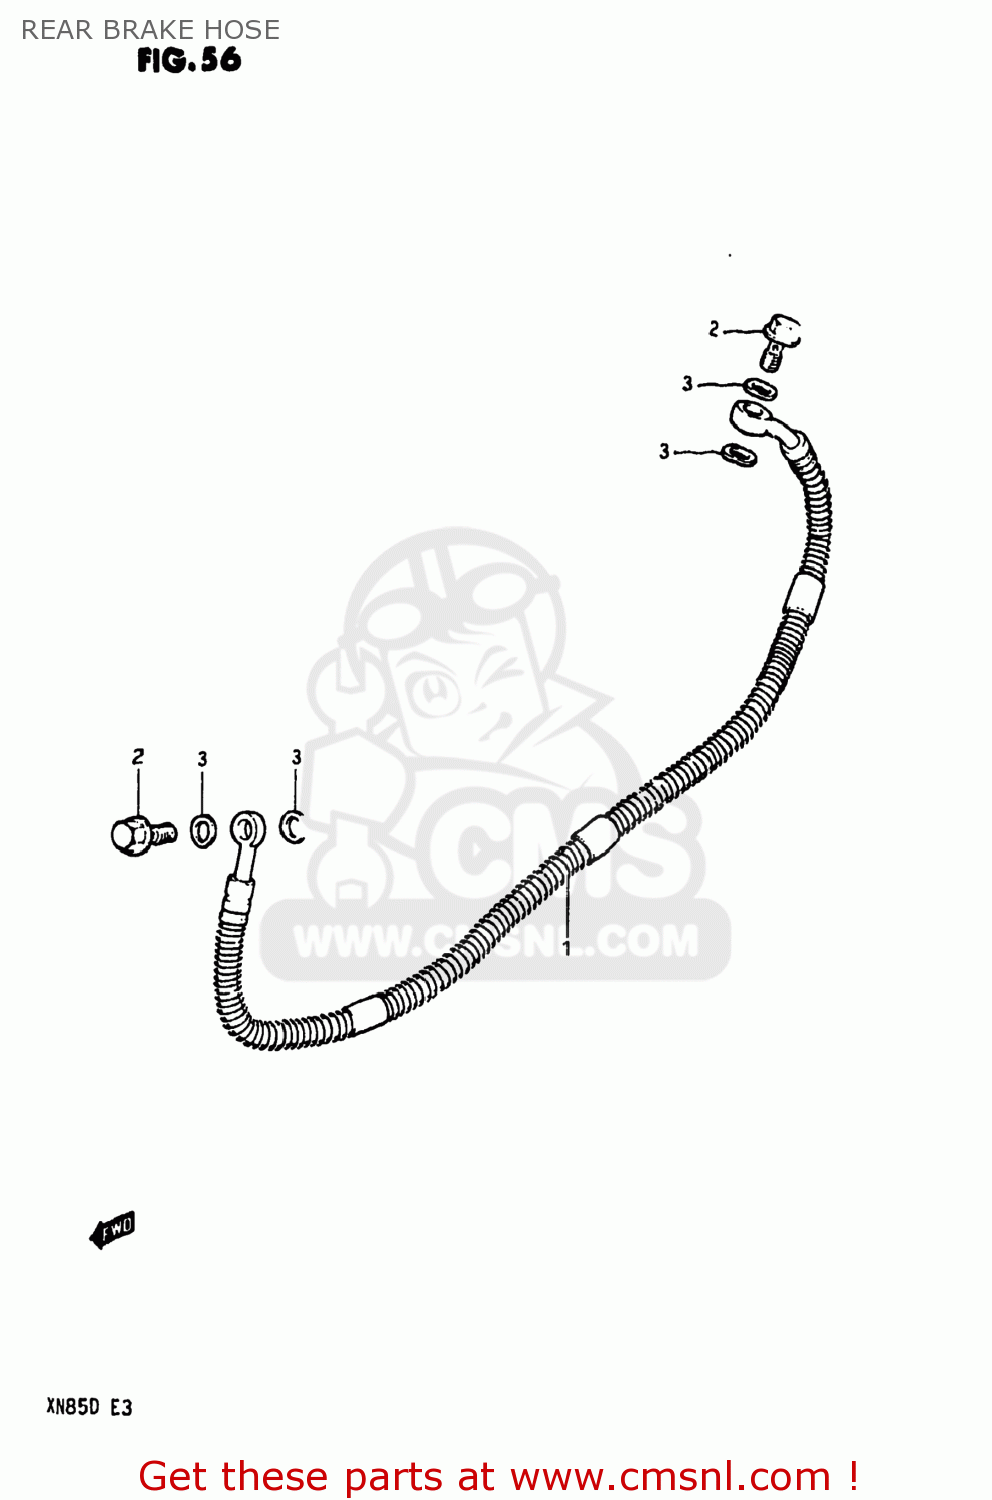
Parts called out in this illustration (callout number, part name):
1	HOSE,REAR BRAKE
2	BOLT,UNION
3	WASHER
